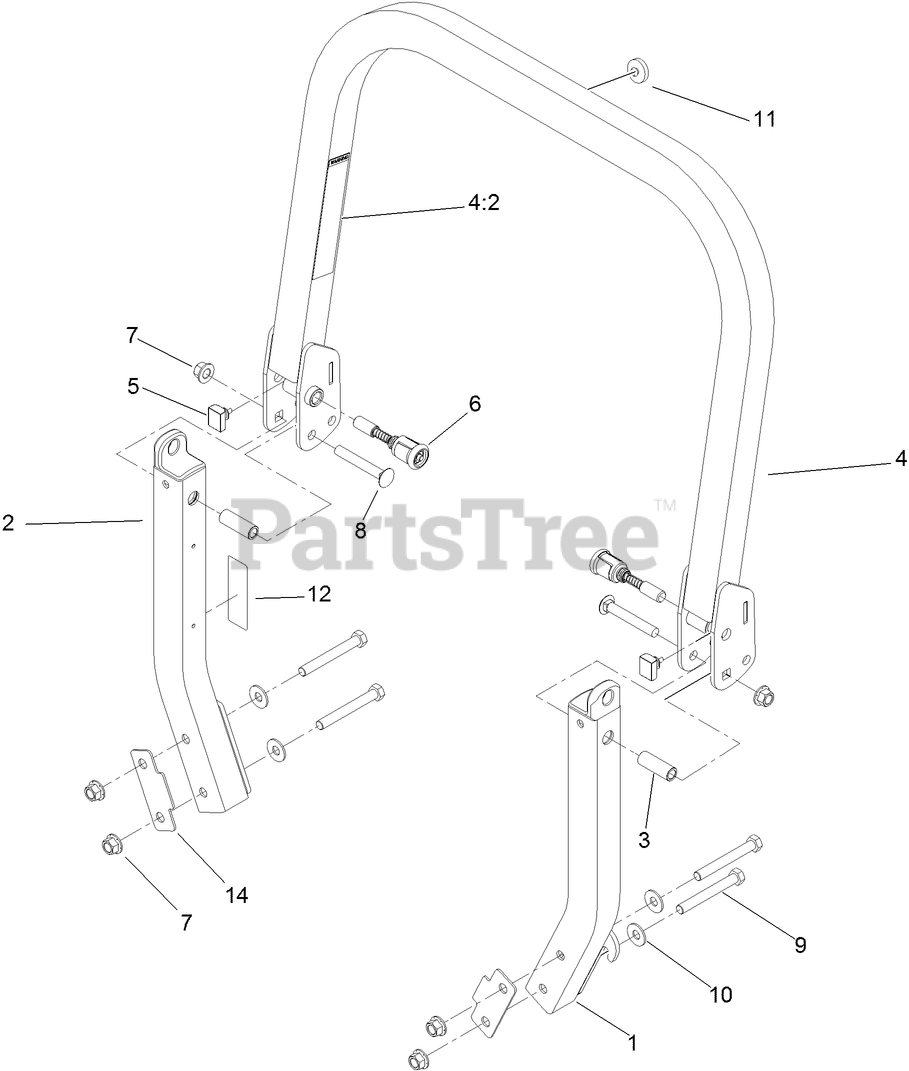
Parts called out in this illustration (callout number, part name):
1	LEG-ROPS, LH
2	LEG-ROPS, RH
3	SPACER
4	UPPER ROPS ASM
4:2	DECAL-WARNING, FOLDING ROPS
5	BUMPER-ROPS
6	PIN-SPRING
7	NUT-LOCK
8	SCREW-CARR
9	SCREW-HH
10	WASHER-SPRING
11	BUMPER-PUSH-IN, RUBBER
12	DECAL-CAUTION
14	SPACER
